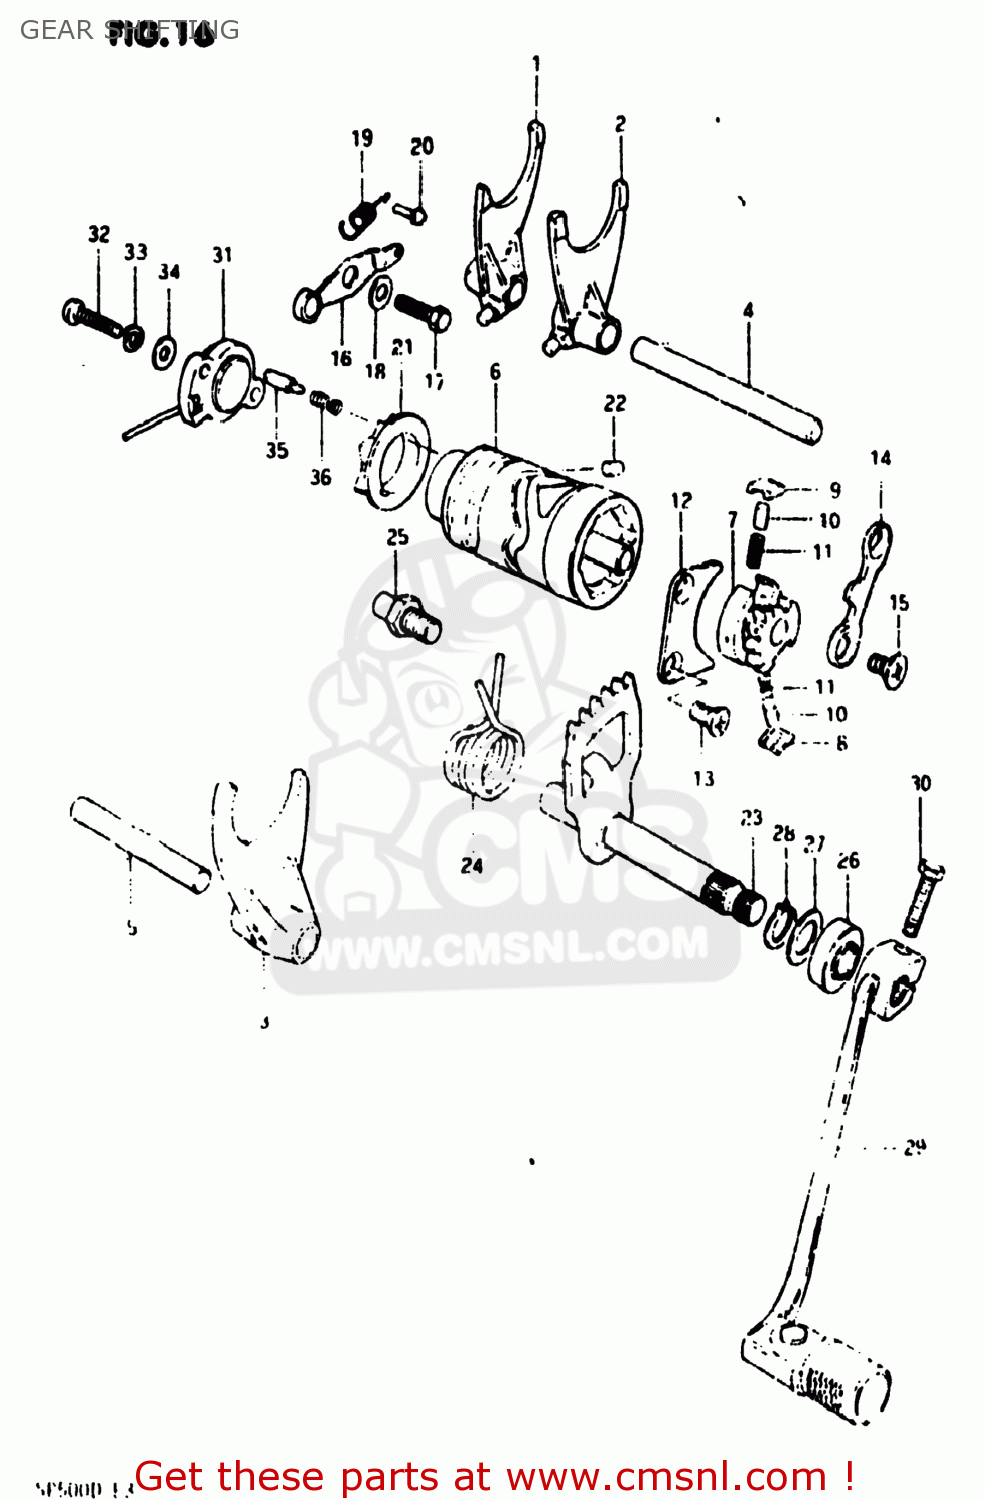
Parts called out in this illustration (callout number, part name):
1	FORK,GEAR SHIFT NO.1
2	FORK,GEAR SHIFT NO.2
3	FORK,GEAR SHIFT NO.3
4	SHAFT,GEAR SHIFT FORK
5	SHAFT,GEAR SHIFT FORK
6	CAM,GEAR SHIFT
7	RETAINER,GEAR SHIFT CAM
8	PAWL,GEAR SHIFT NO.1
9	PAWL,GEAR SHIFT NO.2
10	PIN(5X8)
11	SPRING
12	LIFTER,GEAR SHIFT PAWL
13	SCREW
14	STOPPER,GEAR SHIFT POLE
15	SCREW
16	STOPPER,GEAR SHIFT CAM
17	BOLT
18	WASHER
19	SPRING
20	RIVET
21	PLATE,SHIFT CAM STOPPER
22	PIN 4X6
23	SHAFT,GEAR SHIFT
24	SPRING
25	STOPPER,GEAR SHIFT CAM
26	OIL SEAL
27	WASHER
28	CIRCLIP
29	LEVER ASSEMBLY,GEAR SHIFTING
30	BOLT
31	TERMINAL BASE,NEUTRAL
32	SCREW
33	LOCK WASHER
34	WASHER
35	PIN(5X15.5)
36	SPRING
